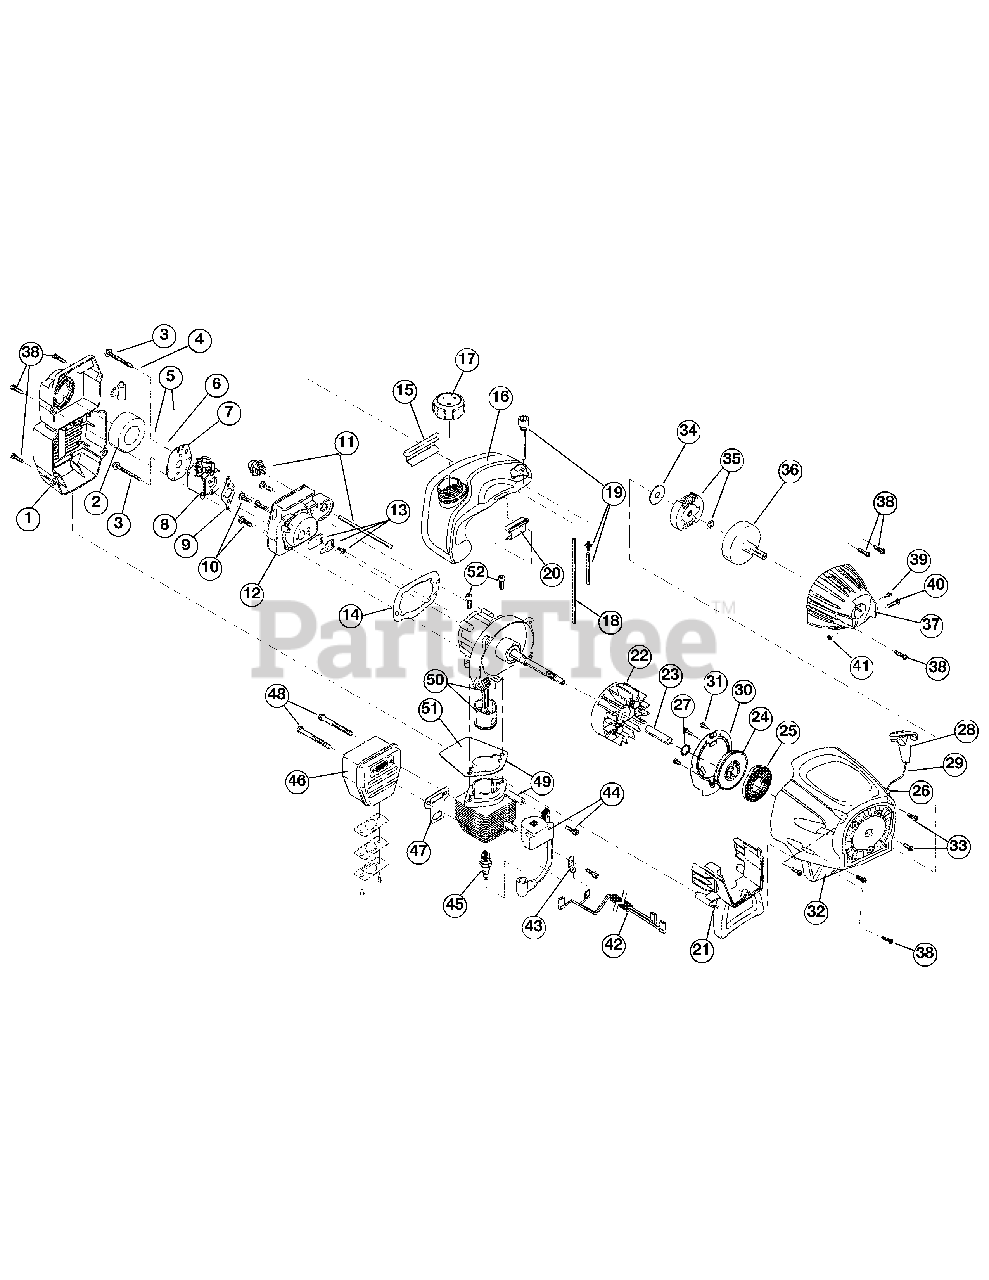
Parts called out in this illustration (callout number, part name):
1	Air Cleaner Cover Assembly (includes 2 & 38)
2	Air Cleaner Filter
3	Carburetor Mounting Screw Assembly
4	Wavey Washer
5	Choke Knob w/Screw
6	Choke Lever (includes 5)
7	Choke Plate (includes 6)
8	Carburetor Assembly (includes 9 & 19)
9	Carburetor Gasket
10	Carb Mount Screw
11	Primer & Hose Assembly
12	Carb Mount Assembly (includes 10, 13 & 14)
13	Reed Assembly
14	Carburetor Mount Gasket
15	Rear Mounting Pad
16	Fuel Tank Assembly (includes 17-19)
17	Fuel Cap Assembly
18	Fuel Return Line
19	Fuel Line Assembly
20	Front Mounting Pad
21	Shroud Extension & Stand (includes 38)
22	Flywheel Assembly
24	Recoil Pulley Assembly (includes 27 & 29)
25	Recoil Spring
26	Rope Guide
27	Pulley Retainer
28	Pull Handle
30	Pressure Plate Assembly (includes 31)
31	Plate Screw
32	Starter Housing Assembly (includes 24-31, 33 & 38)
33	Housing Screw
34	Clutch Washer
35	Clutch Rotor Assembly
36	Clutch Drum Assembly
37	Clutch Cover Assembly (includes 38-41)
38	Cover Screw
39	Anti-Rotation Screw
40	Clamping Screw
41	Clamping Nut
42	Wire Leads and Sleeve
43	Ground Tab
44	Module Assembly
46	Muffler Assembly (includes 47, 48 & spark arrestor)
47	Exhaust Gasket
48	Muffler Mounting Bolts
49	Cylinder Assembly (includes 51 & 52)
50	Piston and Rod Assembly
51	Cylinder Gasket
52	Cylinder Bolt
